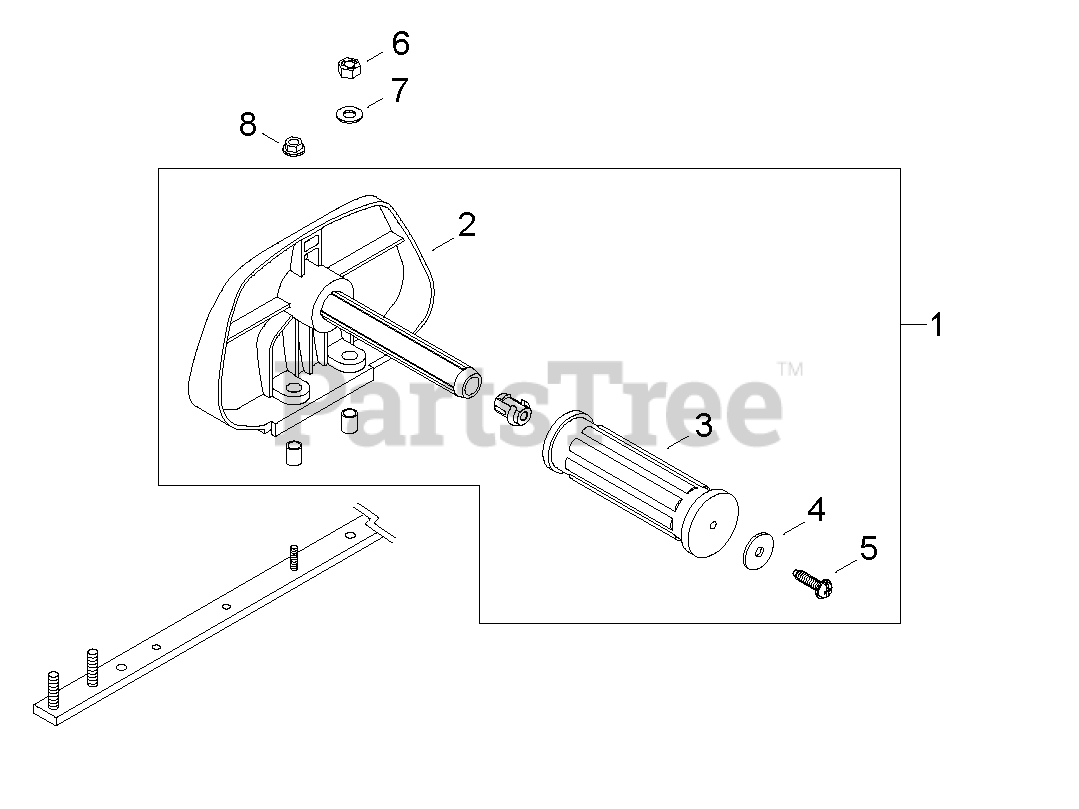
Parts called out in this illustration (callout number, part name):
1	HANDLE ASSY, FRONT
2	HANDLE, FRONT
4	WASHER 5 MM
5	SCREW 5×20
7	WASHER 6.5×13×1
8	NUT, FLANGE M5
